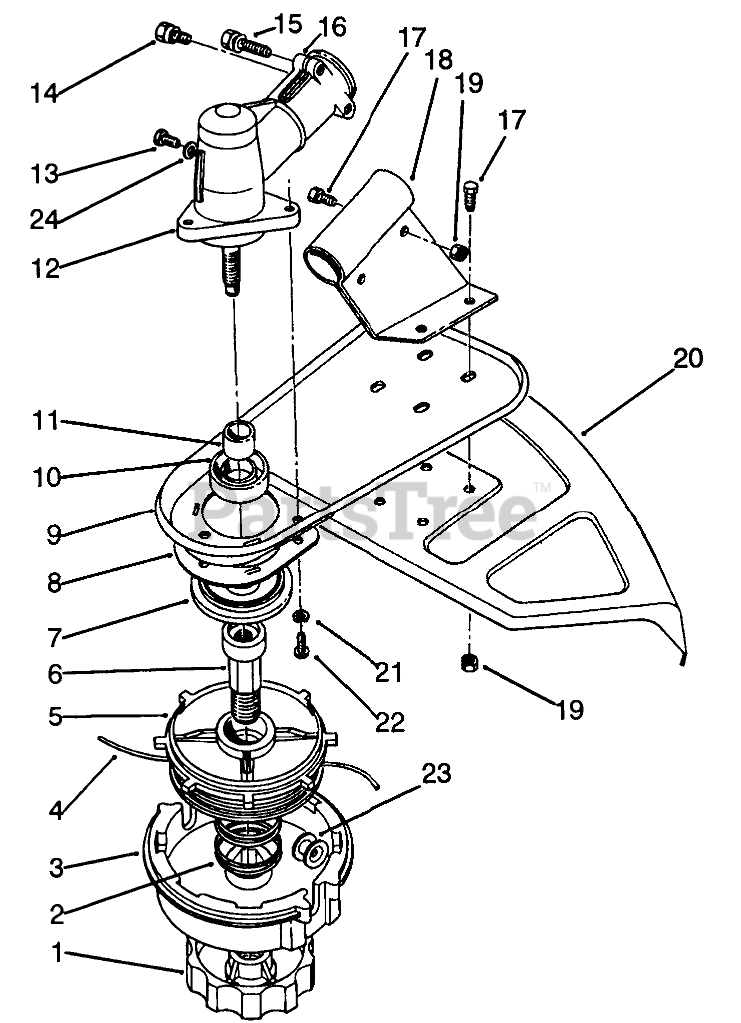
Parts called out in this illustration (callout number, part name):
1	LH KNOB(SERVICE ONLY)
2	SPRING (SERVICE)
3	SPOOL HSG (SERVICE ONLY
4	REPL LINE PKG
5	INNER SPOOL(SERV ONLY)
6	SHAFT (SERVICE ONLY)
7	DUST CAP F/W
8	GRASS WRAP GUARD
9	SHIELD SUPPORT R
10	OIL SEAL
11	SPLINED SLEEVE
12	Gear Box Assembly (Incl. Ref. #10, 11, 13-16 & 24)
13	HHMS SCREW
14	HHMS SCREW
15	HHMS SCREW
16	WASHER
17	SCREW-SHH
18	Bracket-Shield
19	NUT-LOCK, NI
20	GRASS SHIELD-STEEL
21	LOCKWASHER
22	SCREW
23	EYELET(SERVICE)
24	GASKET
